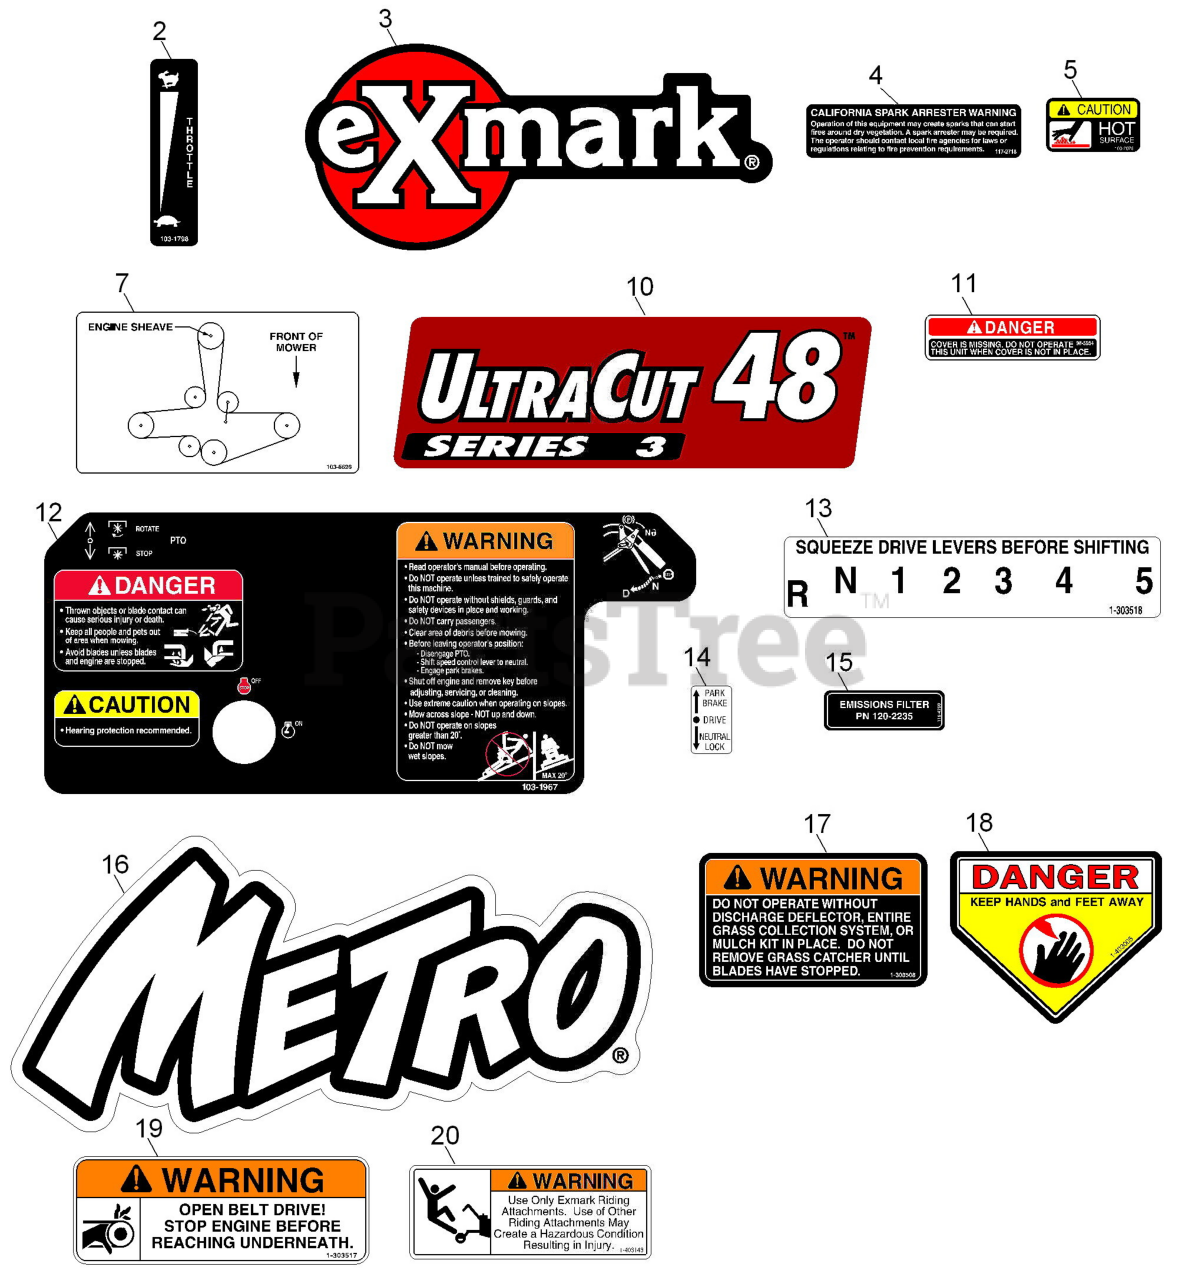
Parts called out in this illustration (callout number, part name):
2	DECAL,THROTTLE ONLY
3	DECAL,EXMARK LOGO
4	DECAL-ARRESTER, SPARK
5	DECAL-CAUTION
7	DECAL,BELT ROUTING
10	DECAL-ULTRACUT 48 SERIES
11	DECAL-COVER, MISSING
12	DECAL,CONSOLE
13	DECAL,SHIFTER
14	DECAL,NEUTRAL/BRAKE
15	DECAL-FILTER, EMISSIONS
16	DECAL,METRO MODEL
17	DECAL-WARNING, DISCHARGE
18	DECAL-DANGER
19	DECAL,BELT DRIVE
20	DECAL,SULKY WARNING
